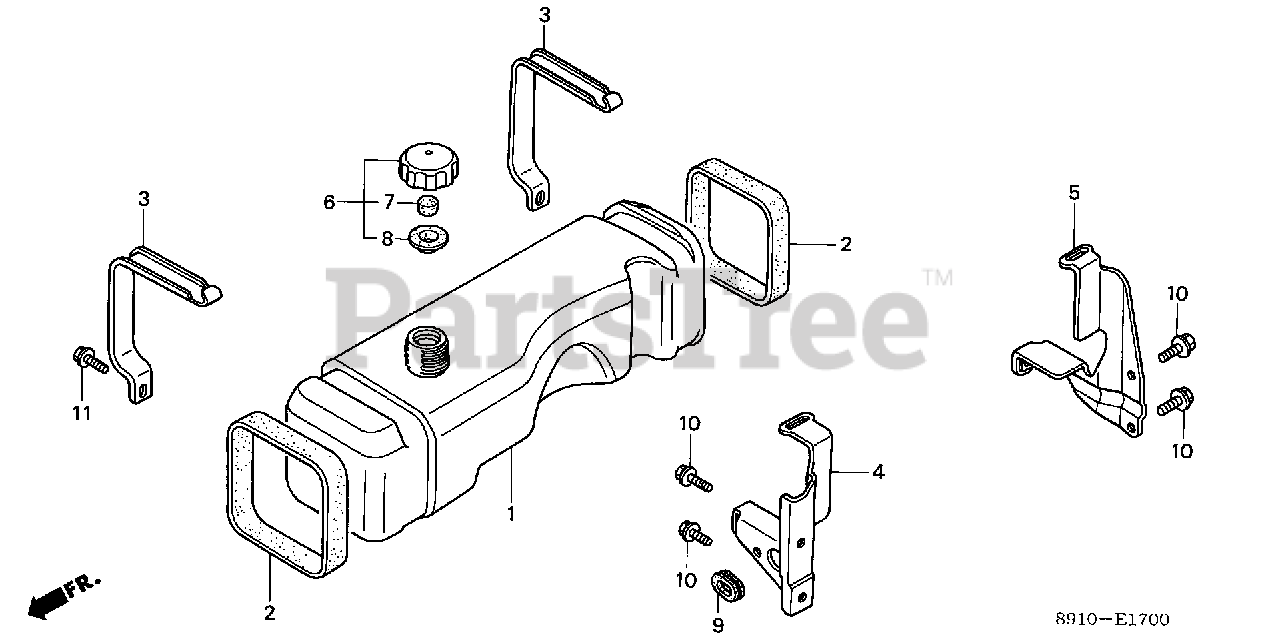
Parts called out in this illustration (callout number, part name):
1	TANK, FUEL
2	RUBBER, FUEL TANK MOUNTING
3	BAND, TANK MOUNTING
4	STAY A, TANK
5	STAY B, TANK
6	CAP ASSY., FUEL TANK
7	SPONGE, FUEL CAP BREATHER
8	GASKET, FUEL CAP
9	GROMMET, WIRE
10	BOLT, FLANGE (6X16)
11	BOLT, FLANGE (6X16)
